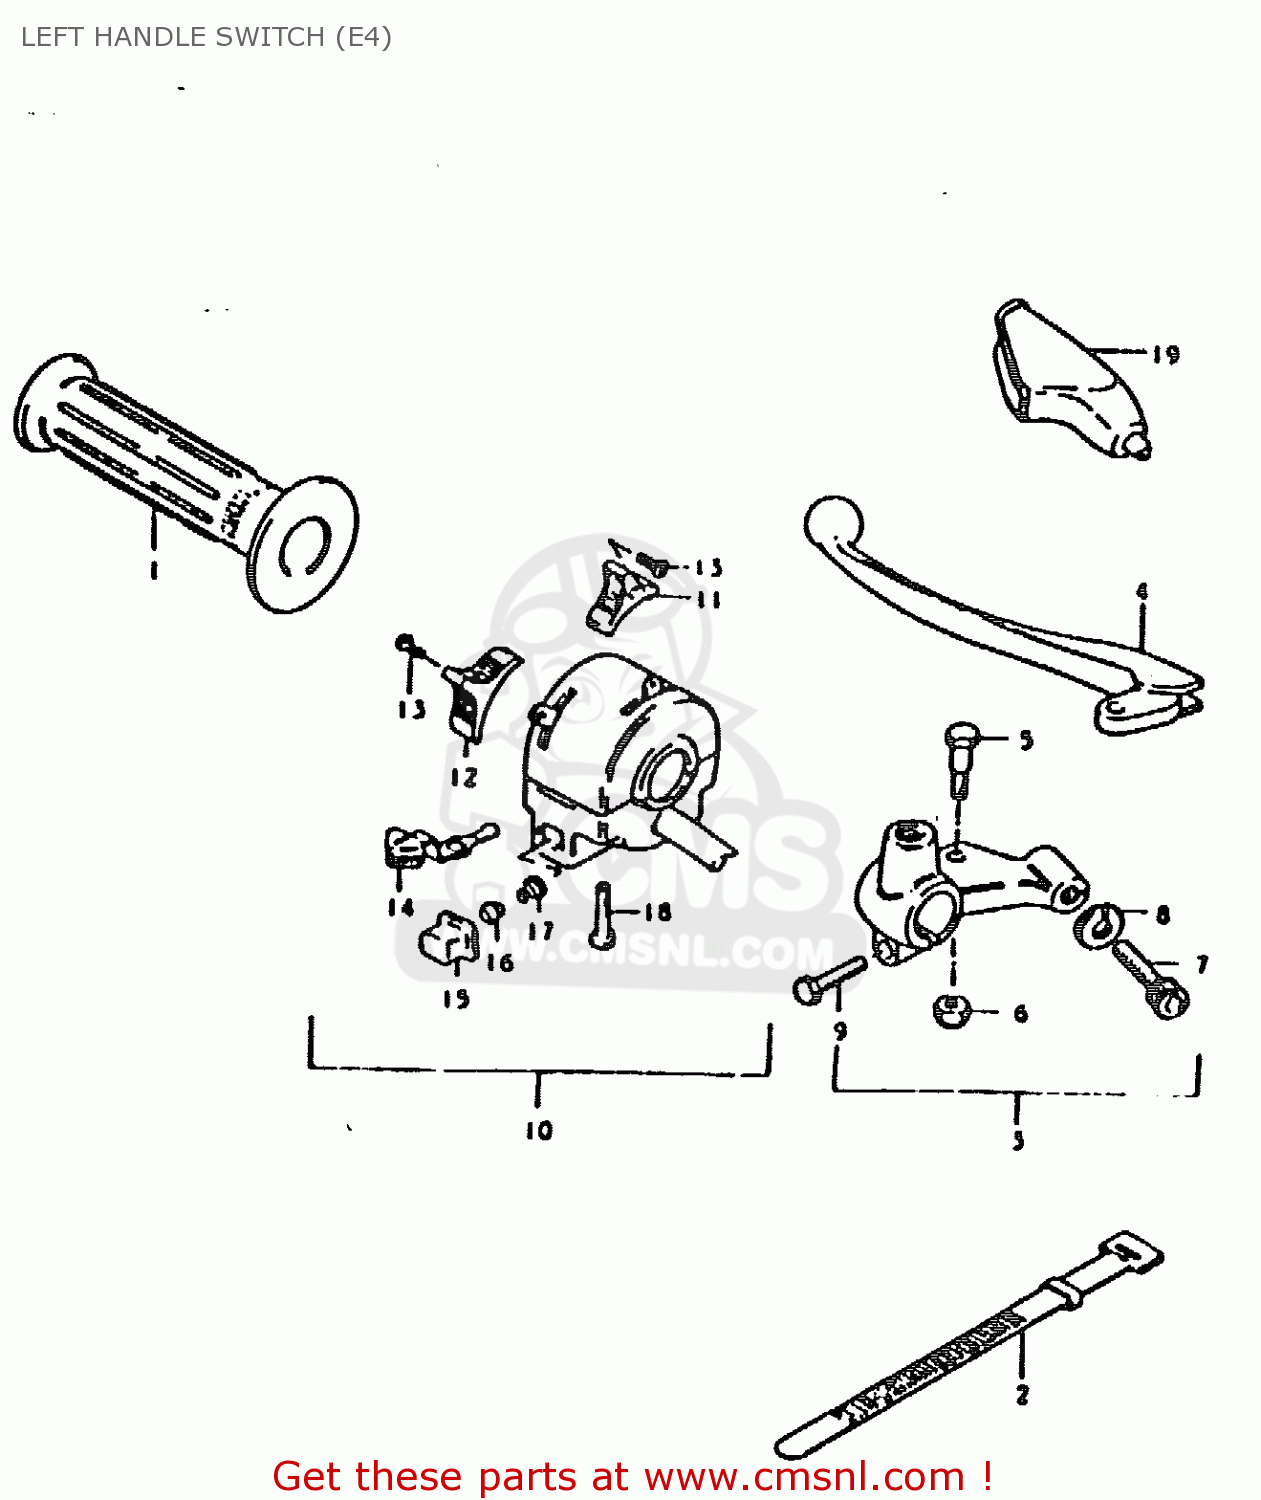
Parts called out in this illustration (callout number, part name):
1	GRIP,L
2	CLAMP(L:120)
3	LEVER ASSEMBLY,CLUTCH
4	LEVER,CLUTCH
5	BOLT,LEVER
6	NUT 6MM
7	ADJUSTER,CABLE
8	NUT,CABLE ADJUSTER
9	BOLT
10	SWITCH ASSY,HANDLE,L
11	KNOB,LIGHTING SWITCH
12	KNOB,DIMMER SWITCH
13	SCREW
14	KNOB,TURNSIGNAL
15	BUTTON,HORN
16	CONTACT
17	SPRING
18	SCREW
19	COVER,CLUTCH LEVER
